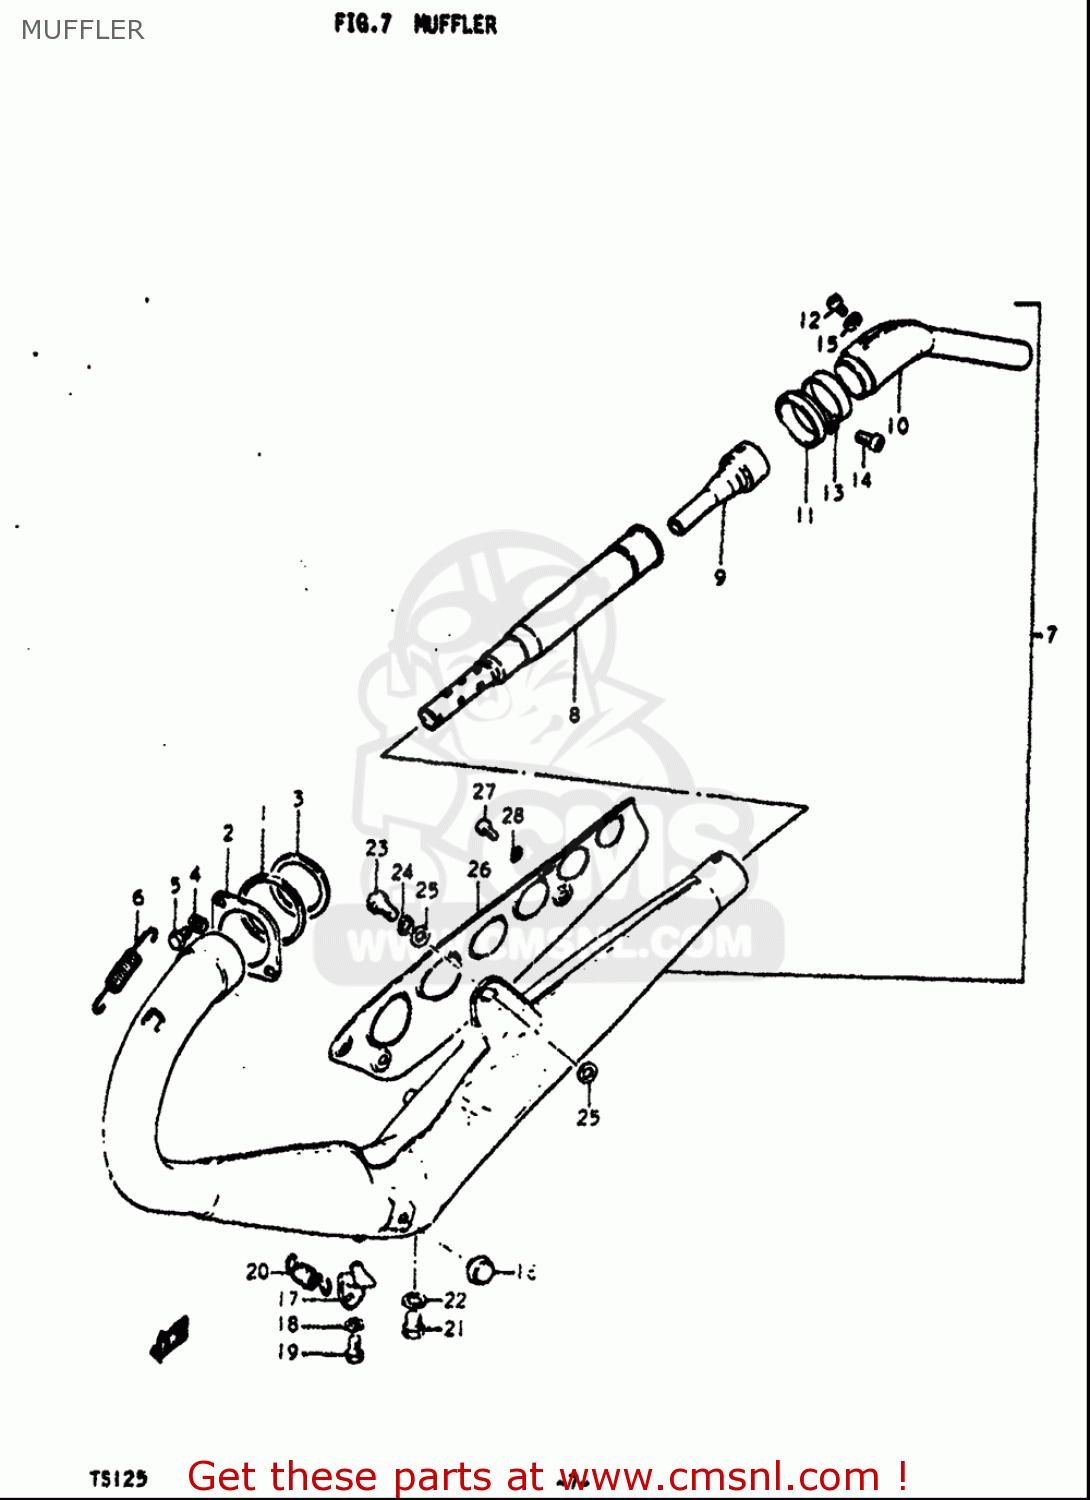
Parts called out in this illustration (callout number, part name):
1	GASKET,EXHAUST PIPE (NAS)
2	CLAMP,EXHAUST PIPE
3	CUSHION,EXHAUST PIPE
4	WASHER,LOCK
5	BOLT
6	SPRING
11	GASKET,MUFFLER TAIL PIPE (NAS)
12	SCREW
13	CLAMP
14	SCREW
16	CUSHION(11.5X22X20)
17	BRACKET, MUFFLER STOPPER
18	WASHER,LOCK
19	BOLT
20	SPRING
21	BOLT 10X9
22	GASKET(10X14X3.6) (NAS)
23	BOLT
24	WASHER,LOCK
25	WASHER
27	SCREW
28	WASHER,LOCK
